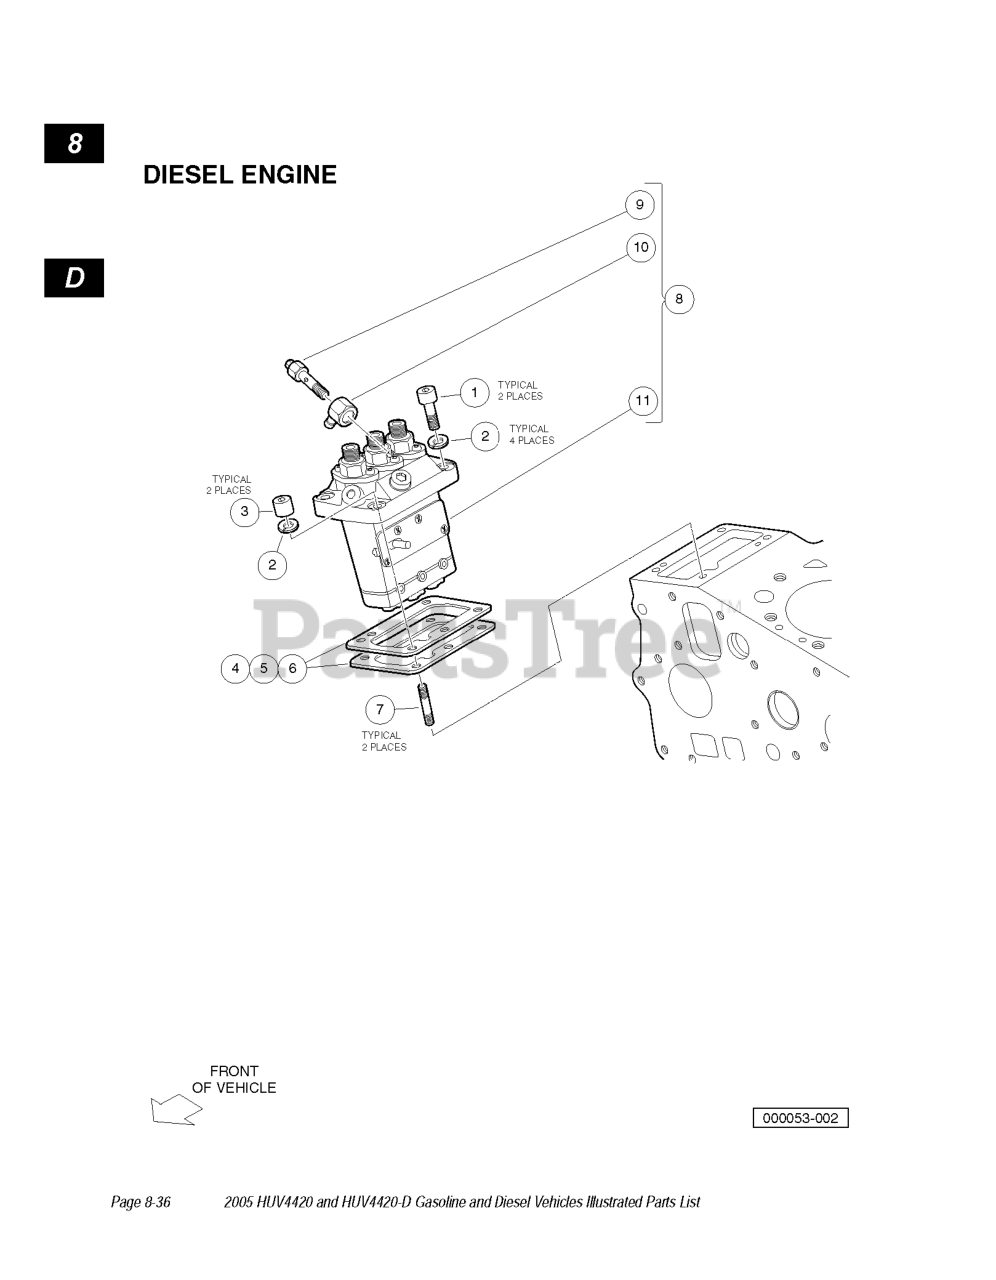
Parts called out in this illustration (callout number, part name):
1	Bolt, Hex-Head, M5 X 0.75 X
3	Nut, Special.
4	SHIM, INJECTION PUMP, 0.20 MM
5	SHIM, INJECTION PUMP, 0.25 MM
6	Shim, Injection Pump, 0.30 mm.
7	Stud, M5 X 25.
8	ASSY-INJ PUMP
10	Joint, Eye
